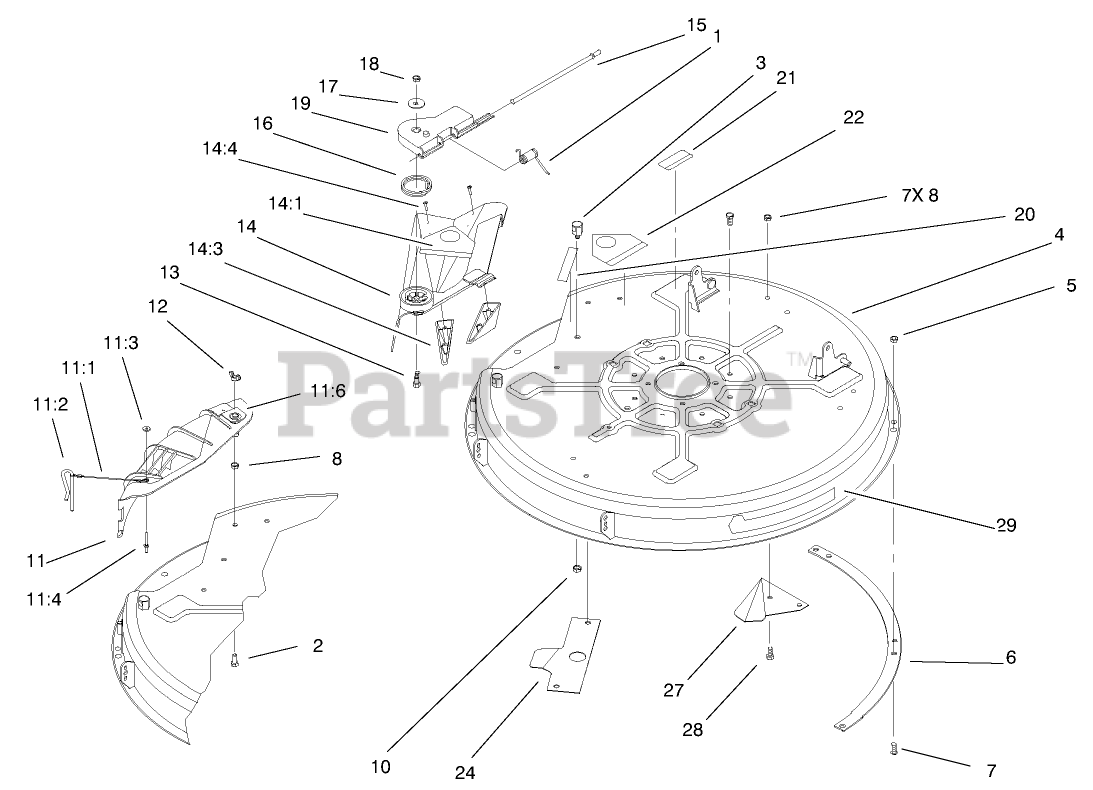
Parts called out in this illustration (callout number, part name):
1	SPRING-TORSION
2	SCREW-HH
3	POST-PIVOT
4	DECK ASM
5	NUT-LOCK, NI
6	RING-DECK
7	SCREW-HH
8	NUT-LOCK, NI
10	NUT-LOCK, NI
11	DISCHARGE COVER ASM
11:1	LANYARD
11:2	PIN-LOCKING, CHUTE
11:3	WASHER-PLAIN
11:4	RIVET-BLIND
12	NUT-WING
13	BOLT-SHOULDER
14	32 INCH DEFLECTOR ASM
14:1	DECAL-DANGER
14:3	KICKER
14:4	SCREW-PPH
15	ROD-HINGE, DEFLECTOR
16	SPRING-TORSION
17	WASHER-FLAT
18	NUT-LOCK, NI
19	PIVOT-HINGE, DEFLECTOR
20	DECAL-DANGER
21	DECAL-WARNING
22	DECAL-DANGER
24	RAMP-DEFLECTOR
28	SCREW-HH
29	DECAL - RECYCLER 32"
